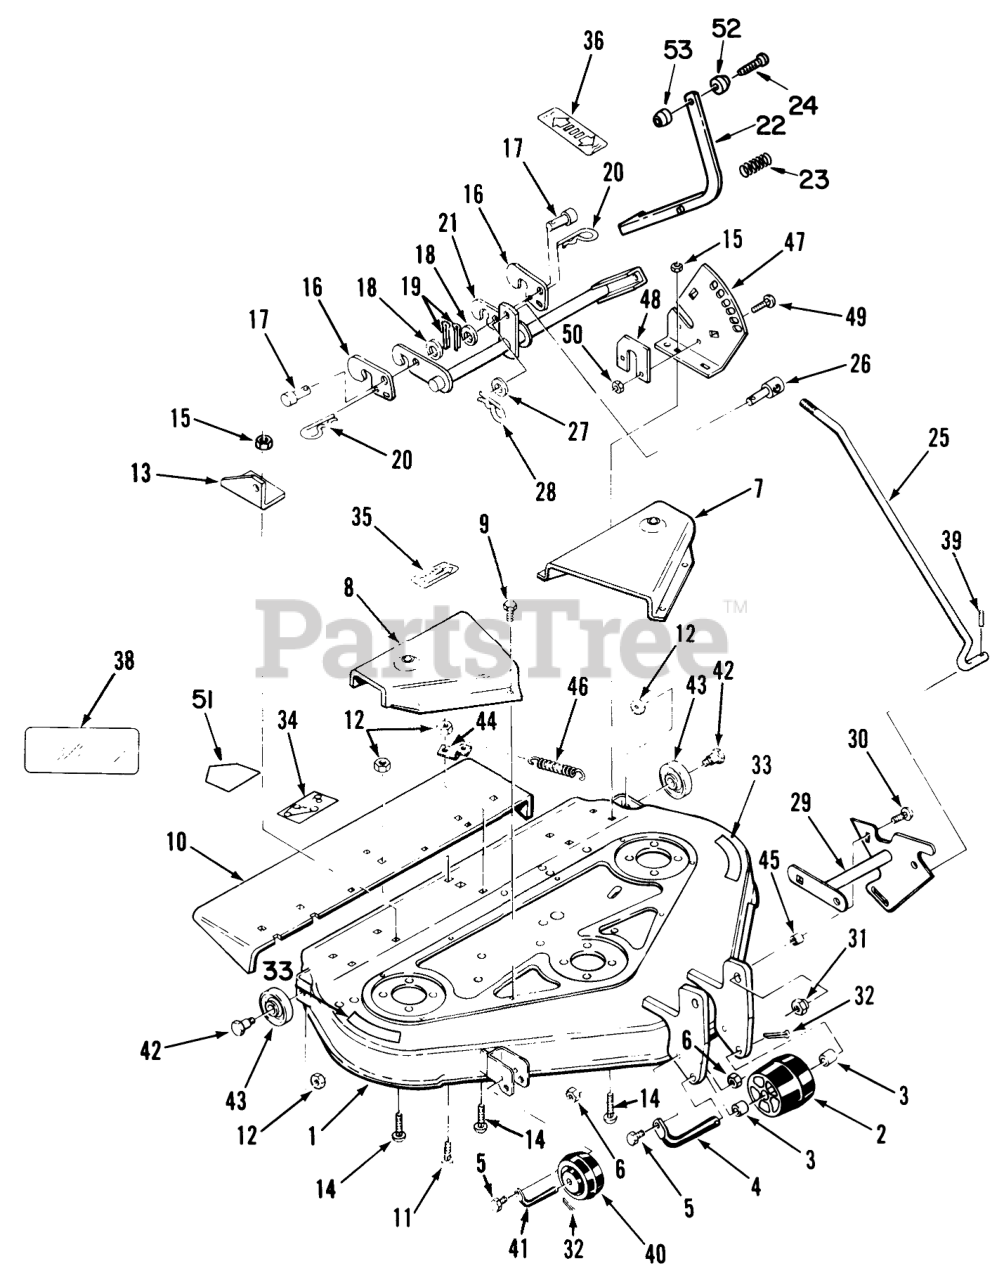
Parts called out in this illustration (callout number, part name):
1	ASS'Y-MOWER DECK R
2	Roller
3	SPACER-ROLLER B
4	SHAFT-ROLLER (FRONT)
5	Bolt
6	Nut
7	SHIELD-BELT LH R
8	SHIELD-BELT RH R
9	Bolt
10	Chute Extension
11	Bolt-Carriage
12	NUT
13	BRACKET-HT ADJ R
14	Bolt
15	NUT
16	LATCH B
18	Washer
19	Cotter Pin
20	Hairpin Cotter
21	WELDMENT-HT ADJ S R
22	WLDMT-LIFT LEVER R
23	SPRING-COMPRESSION
24	BOLT-4
25	ASS'Y-HEIGHT ADJ R
26	STUD-TRUNION
27	Washer
28	Hairpin Cotter
29	ASM-FRONT LIFT R
30	Bolt-Carriage
31	LOCKNUT-FLANGE
32	Cotter Pin
33	DECAL - DANGER
34	DECAL-BELT INSTALLAT
35	DECAL-BELT ADJUST
36	DECAL-HOC
38	DECAL-OVERLAY
39	SPIROL PIN
40	ROLLER
41	SHAFT-ROLLER
42	BOLT-SHOULDER
43	WHEEL-GAGE
44	ANCHOR-SPRING R
45	SPACER
46	SPRING-EXTENSION
47	QUADRANT R
48	PLATE-RETAINING R
49	Bolt
50	Nut
51	DECAL-DANGER
52	KNOB
53	KNOB
